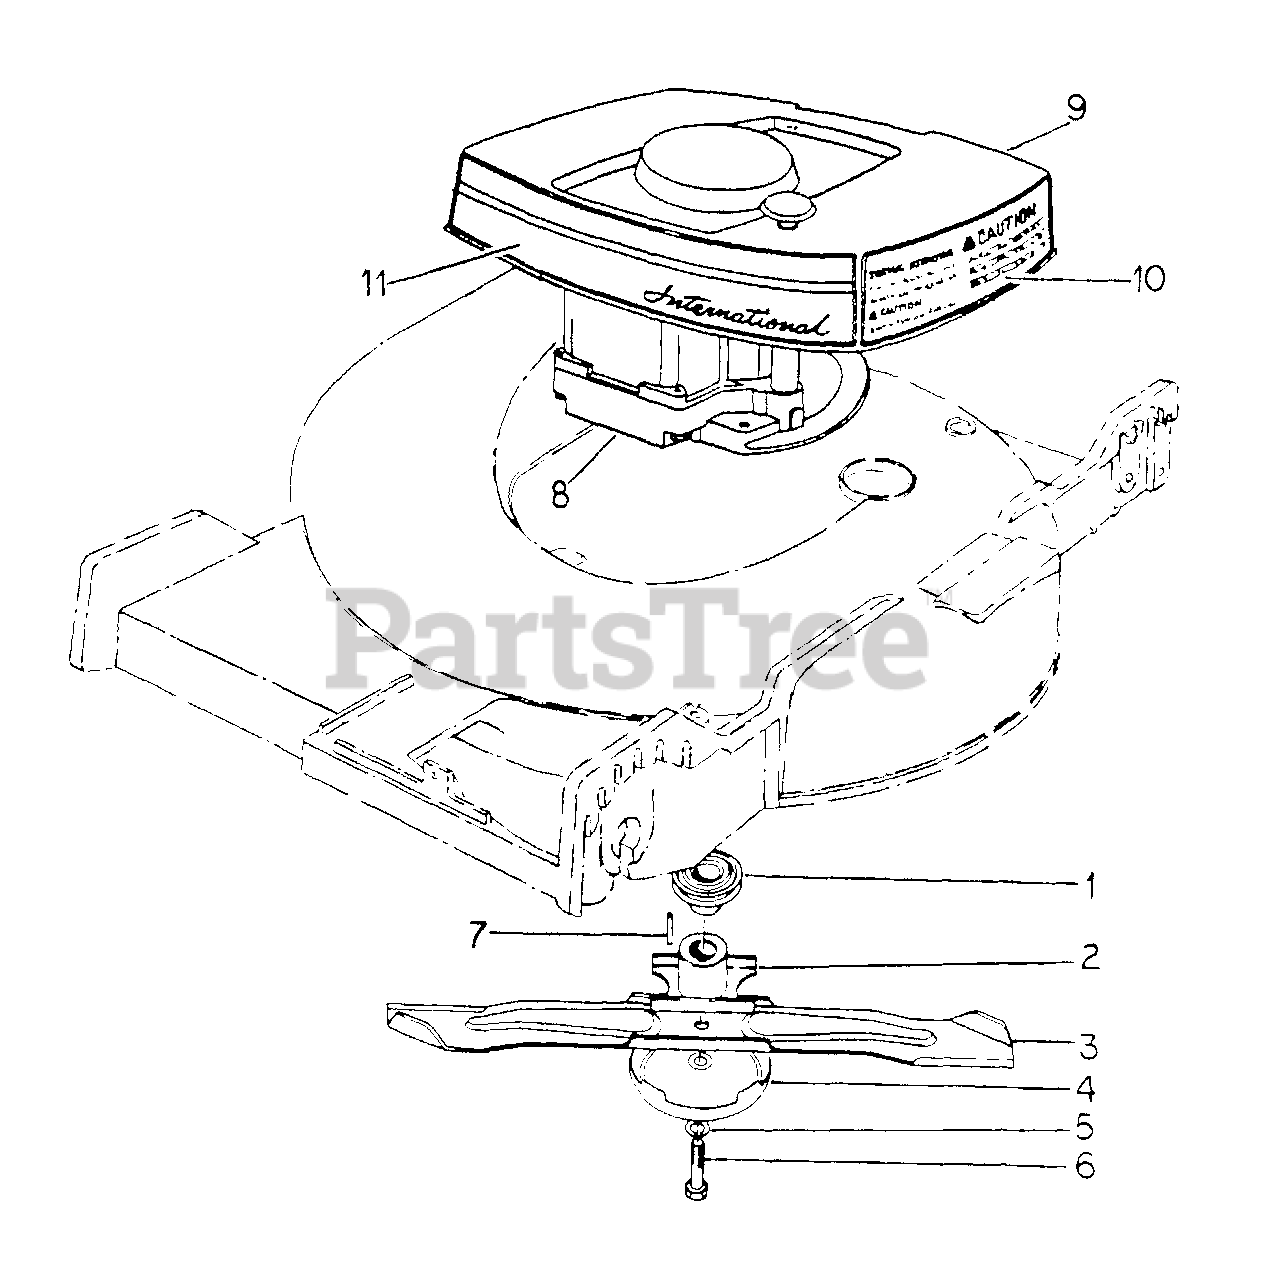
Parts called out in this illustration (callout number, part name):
1	PULLEY, DRIVE
2	RETAINER, BLADE
3	BLADE, 21 IN. CUTTING
4	CUP, ANTI-SCALP
5	WASHER, 7/16 HEAVY LOCK
6	SCREW, BLADE
7	KEY, 3/16 X .50 SQ PARALLEL
8	ENGINE ASSY, 4 HORSEPOWER
9	SHROUD, ENGINE
10	PRODUCT GRAPHIC, CAUTION AND STARTING INSTRUCTIONS
11	PRODUCT GRAPHIC, INTERNATIONAL NAME TRADEMARK
